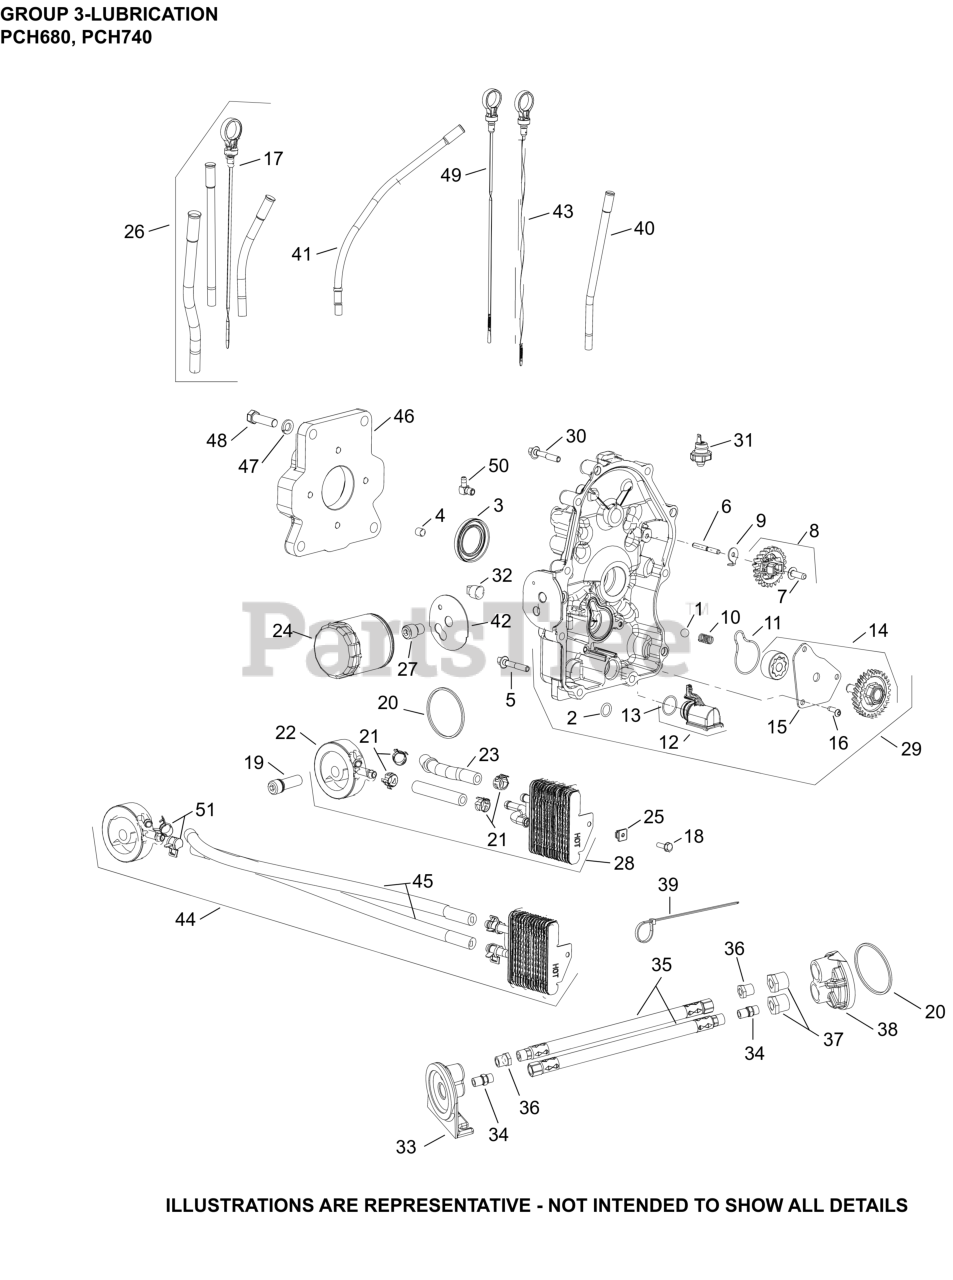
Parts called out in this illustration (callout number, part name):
1	PRESSURE RELIEF BALL
4	PLUG, CTSK PIPE 1/8"
5	SCREW, FLG M8X1.25X45
6	SHAFT, GOVERNOR GEAR
7	PIN, GOVERNOR REGULATING
8	KIT, GOVERNOR GEAR W/PIN
9	TAB, LOCKING
10	SPRING, COMPRESSION
11	SEAL, OIL PUMP COVER
12	PICK-UP ASSEMBLY, OIL
13	O-RING, OIL PICK-UP
14	PUMP ASSEMBLY, OIL
15	COVER, OIL PUMP
16	SCREW, BUTTON HEAD
18	SCREW, TAP M6X1.7X18
19	NIPPLE, OIL FILTER - (#2413608S)
20	O-RING, OIL COOLER
21	CLAMP, HOSE LOW PROFILE
22	ADAPTER, OIL FILTER (CH EFI)
23	HOSE, OIL COOLER
24	OIL FILTER
25	NUT, PLASTIC - BLACK
26	KIT, DIPSTICK/DIPSTICK TUBES
28	COOLER, OIL ASSEMBLY
29	KIT, CLOSURE PLATE ASSY
30	SCREW, HEX FLANGE
